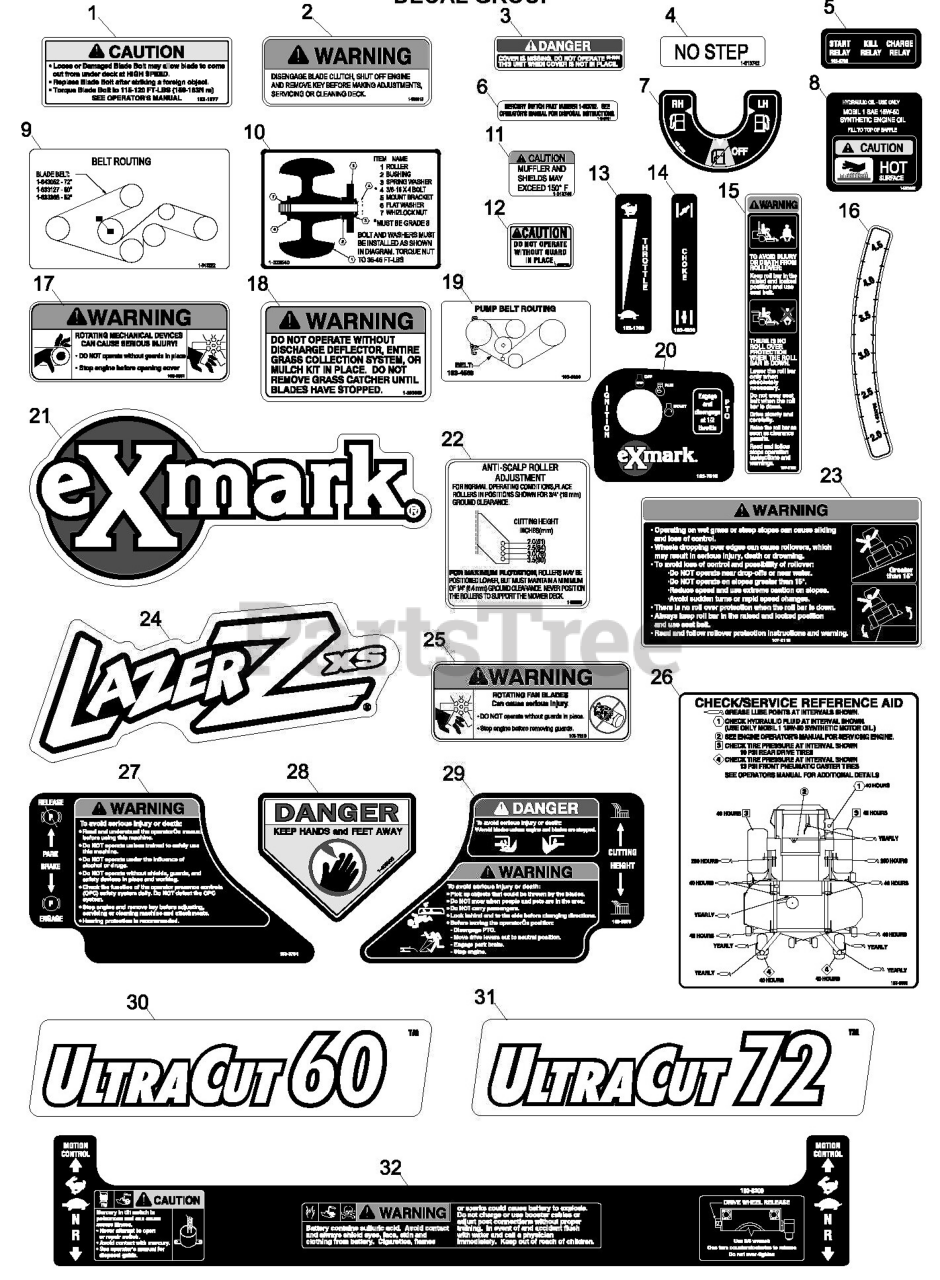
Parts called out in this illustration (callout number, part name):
1	DECAL,BOLT TORQUE
2	DECAL,WARNING
3	DECAL-COVER, MISSING
4	DECAL,NO STEP
5	DECAL,RELAY
6	DECAL-SWITCH, MERCURY
7	DECAL-VALVE, FUEL
9	DECAL,BELT ROUTING
10	DECAL,ROLLER MOUNTING
12	DECAL-GUARD
13	DECAL,THROTTLE ONLY
14	DECAL,CHOKE
15	DECAL-WARNING, FOLDING RO
16	DECAL-HEIGHT, DECK
17	DECAL-DEVICES, ROTATING
18	DECAL-WARNING, DISCHARGE
19	DECAL,PUMP BELT ROUTING
21	DECAL,EXMARK LOGO
22	DECAL,ANTISCALP
23	DECAL-WARNING
24	DECAL,LAZER XS MODEL
25	DECAL,PUMP FAN WARNING
27	DECAL,PARK BRAKE
28	DECAL-DANGER
29	DECAL,CUTTING HEIGHT
30	DECAL,ULTRACUT 60
31	DECAL,ULTRACUT 72
32	DECAL,CONSOLE TOP
